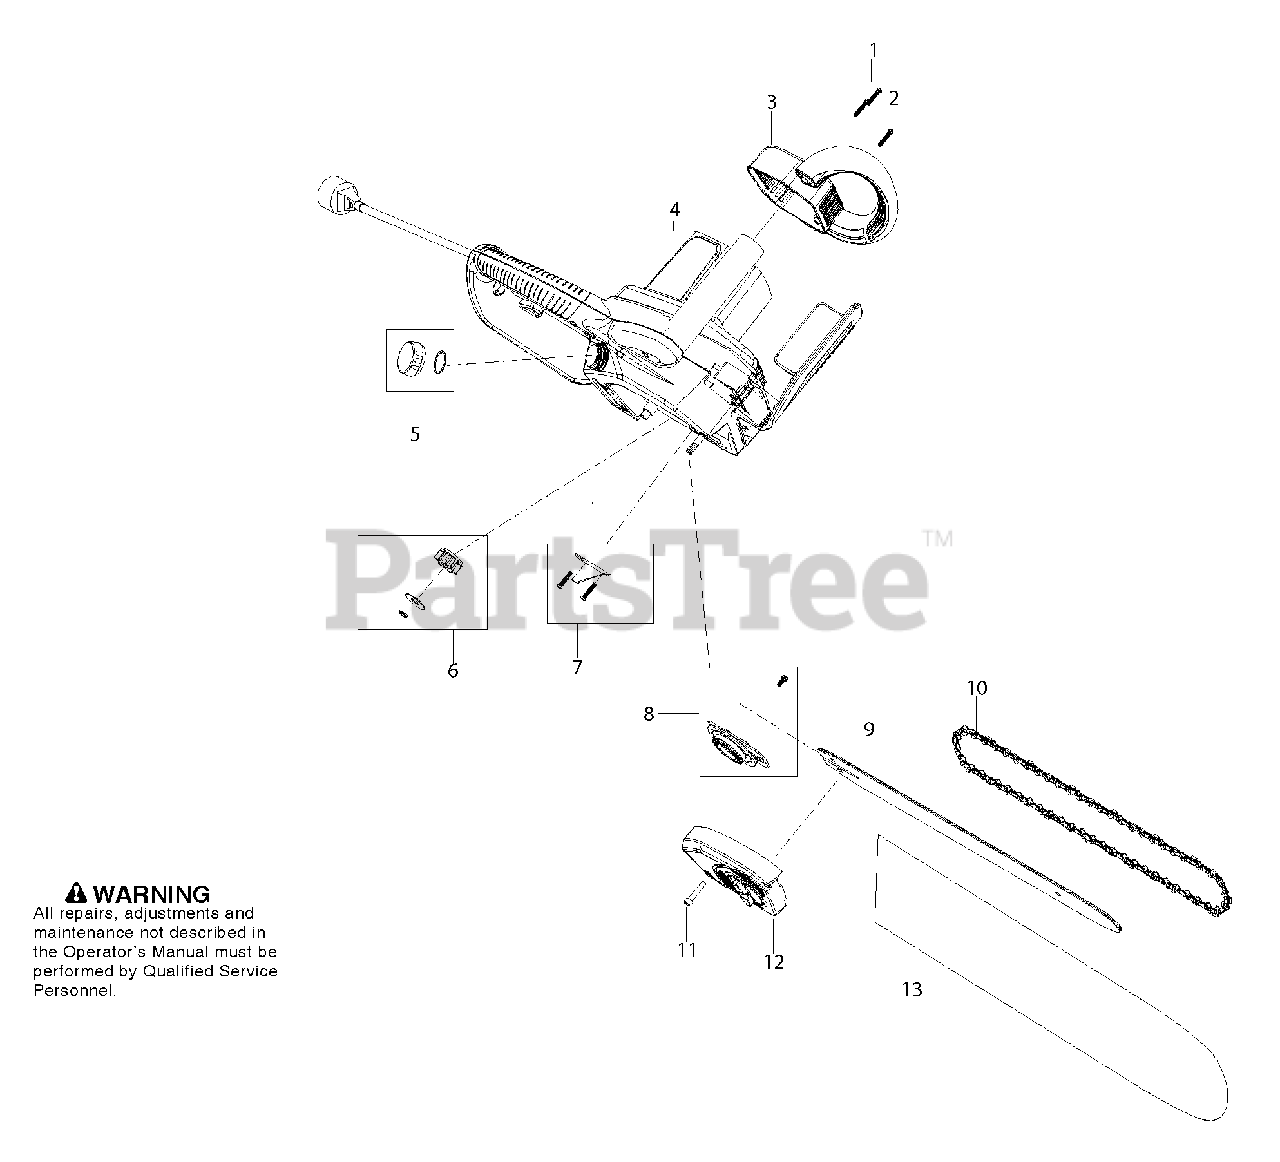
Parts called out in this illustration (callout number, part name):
1	Screw (2 Pack)
3	Motor Cover
4	Assy - Electric Saw
5	Assy - Oil Tank Cap
6	Kit - Sprocket
7	Kit - Chain Catcher
8	Kit - Adjuster Wheel
12	Assy - Bar Clamp
13	Scabbard
